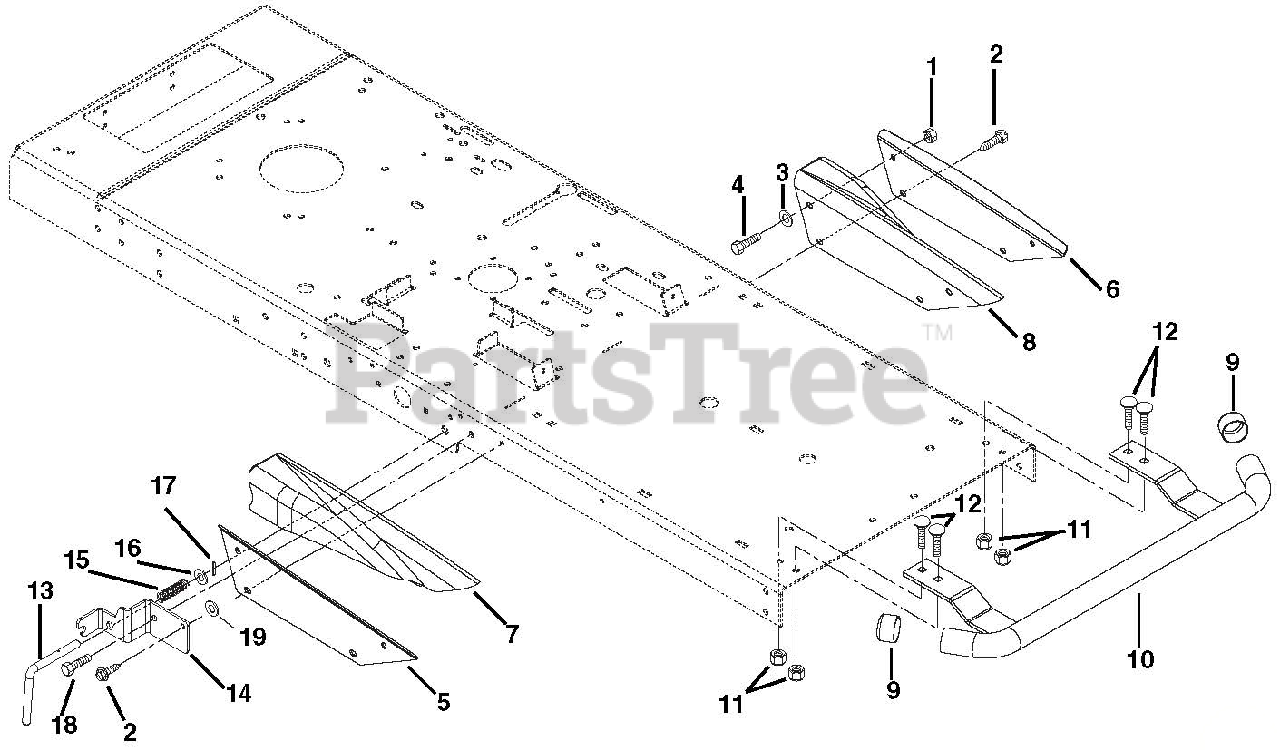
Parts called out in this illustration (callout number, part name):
1	@NUT-LK-NYL .312-18 YWZC
2	@SCR-TAP .31-18X.75 HWH TR YWZ
3	@WSHR-FL-STL.344X.688X.065YWZC
4	@BLT-HEX .31-18X.75 GR5 YWZC
5	BRACKET, RAIL SUPPORT RH
6	BRACKET, RAIL SUPPORT LH
7	RAIL, SIDE RH
8	RAIL, SIDE LH
9	SLEEVE CAP
10	BUMPER, WLDM'T
11	@NUT-LK-NYL .38-16 YWZC
12	@BLT-RDHDSQNK .38-16X1.00 G5YZ
13	PIN-INDEX
14	BRACKET-STOP
15	SPRG, COMP .058X.65X2.13 WLD15
16	@WSHR-FL-STL.531X1.06X.095YWZC
17	PIN-ROLL .156X1.00
18	@BLT-HEX .38-16X1.00 GR5 YWZC
19	WSHR-FL-STL .406X1.00X.188 YWZ
